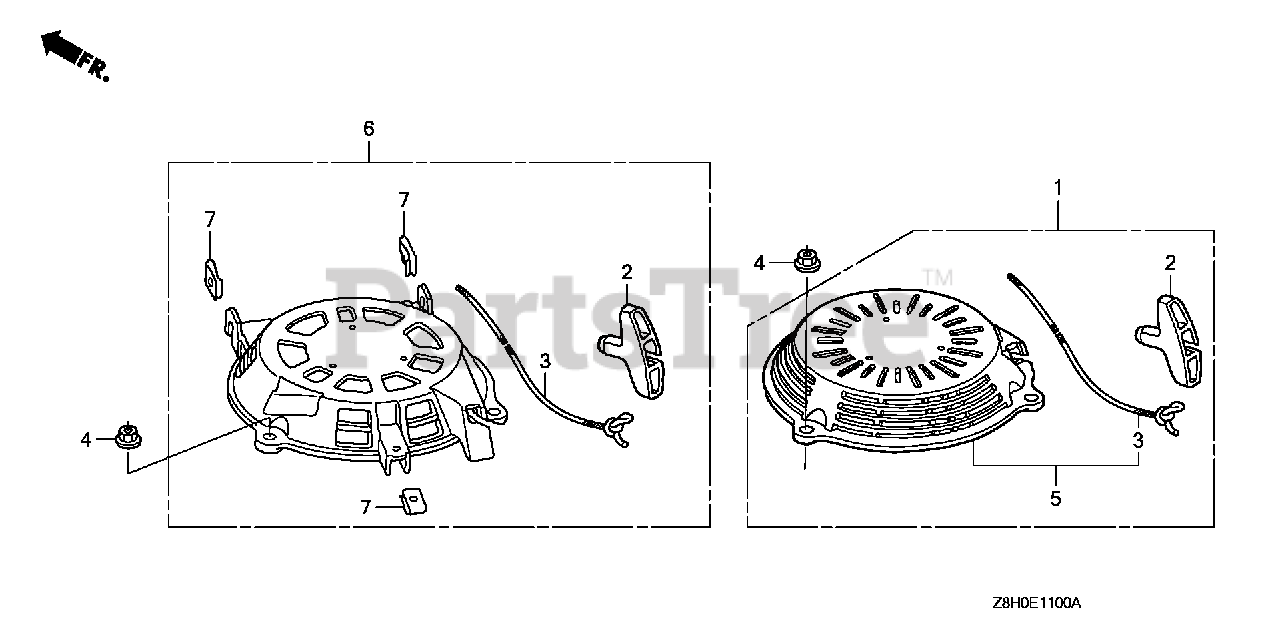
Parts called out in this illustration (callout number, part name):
1	STARTER ASSY., RECOIL *NH1* (LONG ROPE) (BLACK)
2	GRIP, STARTER
3	ROPE, RECOIL STARTER (LONG TYPE)
4	NUT, FLANGE (6MM)
